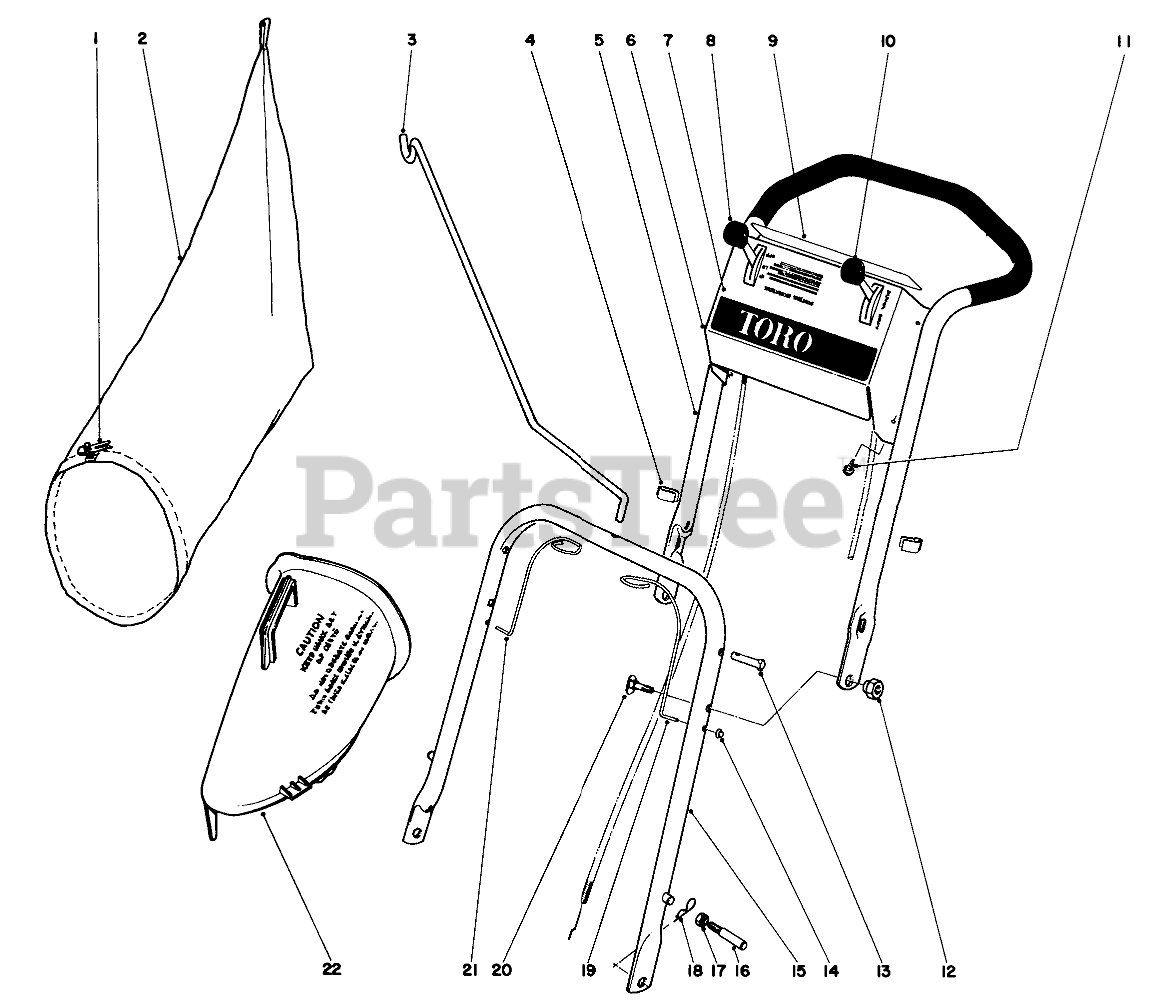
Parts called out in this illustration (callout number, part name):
1	BAG CORD FASTENER
2	Grass Bag (Incl. Ref. No. 1)
3	Bag Hanger Rod
4	BOWDEN CLIP
5	Upper Handle
6	Control Plate
7	Decal, Control Plate
8	Throttle Control
9	Decal, Safety
10	Traction Control
11	SCREW-HWHTF
12	Pivot Nut
13	Latch Pin
15	Lower Handle
16	Handle Pin
17	Nut
18	PIN-COTTER, HAIR
19	Latch Spring L.H.
20	HANDLE SCREW
21	Latch Spring R.H.
22	BAG ATTACHMENT
